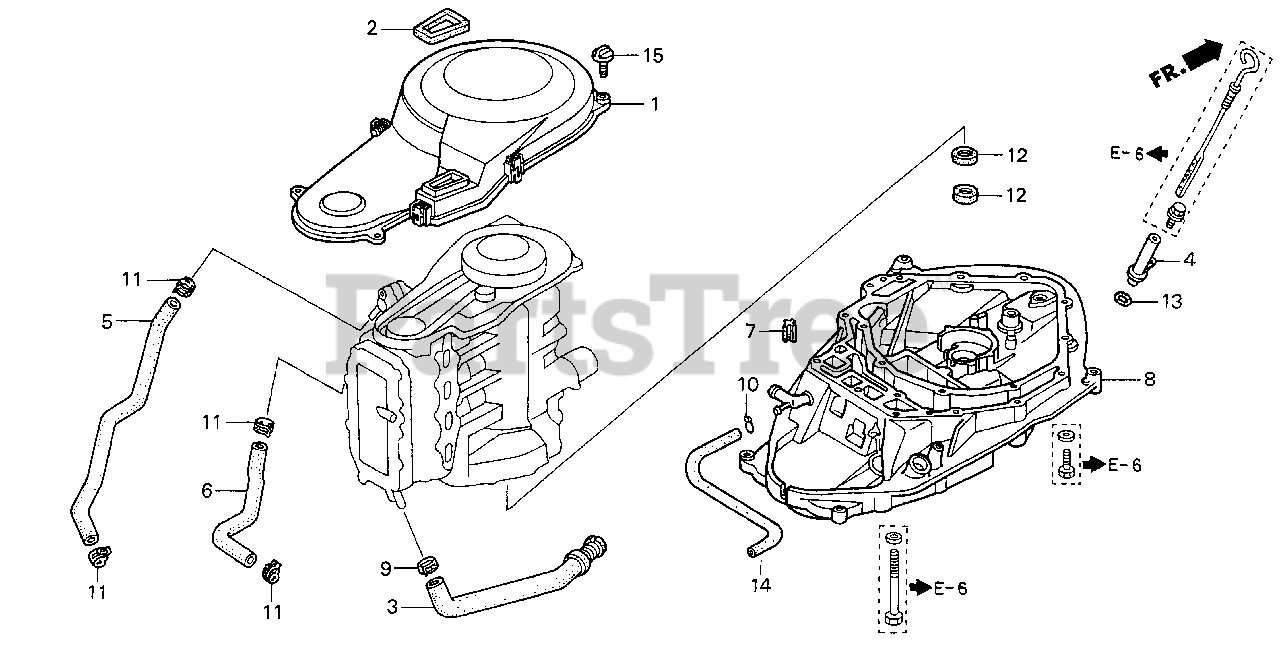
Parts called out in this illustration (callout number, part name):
1	COVER, TIMING BELT (UPPER)
2	RUBBER, SEAL
4	PIPE, OIL LEVEL
5	HOSE, FLUSHING WATER
6	HOSE, WATER BYPASS
7	RUBBER, SEAL
8	CASE, MOUNT *NH8* (DARK GRAY)
9	CLAMP, TUBE (D22)
10	CLIP, TUBE (B8)
11	CLAMP, TUBE (D18.8)
12	SEAL, WATER (22X35X7)
13	O-RING (11.5X3.5)
14	BULK HOSE, VACUUM (4.5X1000) (4.5X430)
